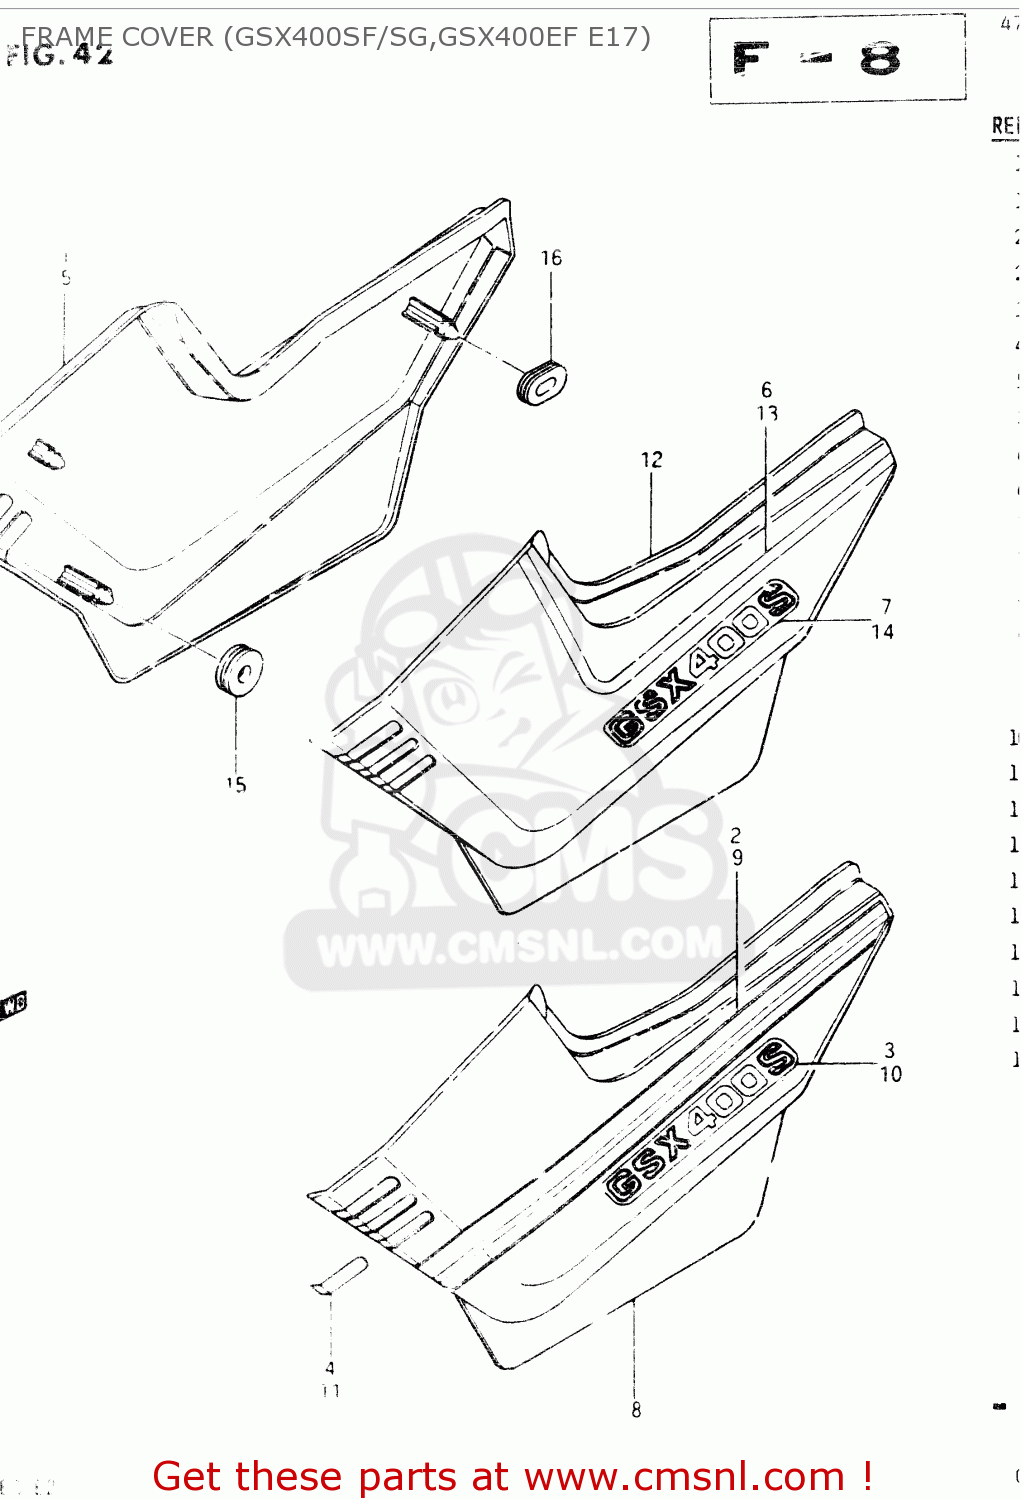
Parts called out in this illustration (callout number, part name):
1	COVER, FRAME RH
2	TAPE SET, FRAME COVER RH
3	EMBLEM (WHITE)
4	LABEL,FRAME COVER DENT,R
5	COVER, FRAME RH
6	TAPE SET, RH (GOLD)
7	EMBLEM (BLACK)
8	COVER, FRAME LH
9	TAPE SET, FRAME COVER LH
10	EMBLEM (WHITE)
11	LABEL,FRAME COVER DENT
12	COVER, FRAME LH
13	TAPE SET, LH (GOLD)
14	EMBLEM (BLACK)
15	CUSHION
16	CUSHION
